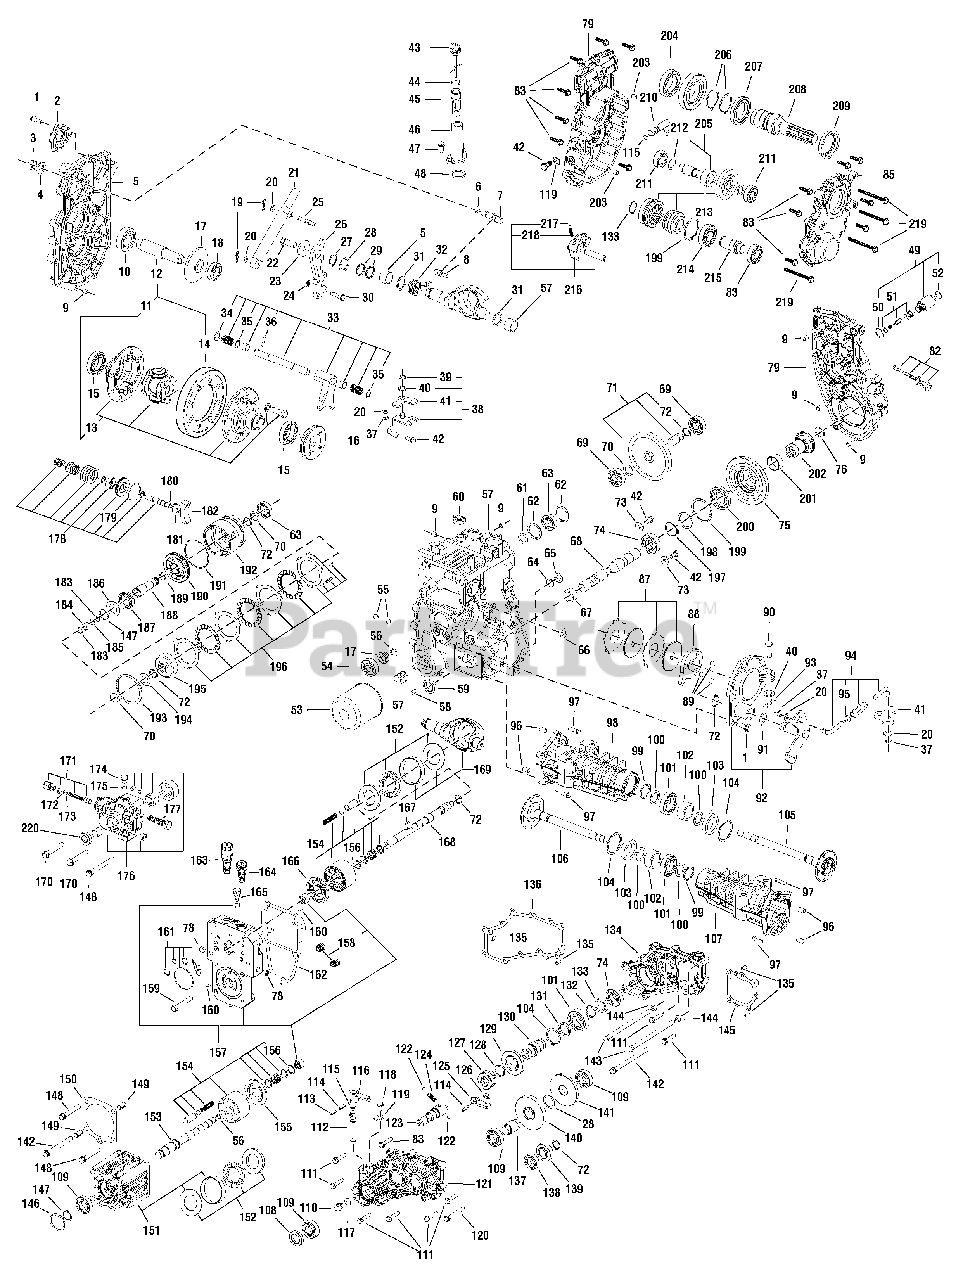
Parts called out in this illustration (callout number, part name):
2	COVER PTO BRAKE
5	COVER KIT MISSION
6	O-RING, 1A P10A
8	SPRING CENTERING
9	COLLAR 8*10*11.5
10	BEARING TMB305
11	FINAL GEAR KIT
12	SHAFT FINAL PINION
13	DIFF GEAR KIT
15	BEARING 6007
16	SLIDER DIFF LOCK
17	GEAR KIT INPUT
18	BEARING 6005SH2
21	ABSORBER SHOCK
23	WASHER 44*14*4.5
24	PUSH NUT 7.8
26	ARM CONTROL
28	WASHER 29*35*1
29	PACKING P26
30	PIN ARM CONTROL
31	WASHER 38*38*2
33	FORK KIT DIFF LOCK
34	SPACER 16.5*24*1
36	PIN 4.0A*25
38	FULCRUM KIT DIFF
44	PACKING P18
45	PIPE OIL PORT
47	TAPPING SCREW 8*20
48	PACKING P32
49	SOLENOID ASSY
50	GASKET SOLENOID
51	VALVE ASSY SOLENOID
52	PACKING P18
54	BEARING TMB303C
57	HOUSING KIT MISSION
59	SEAL TC253807
61	PACKING 19017
63	BEARING 6004
66	SEAL TC162606
67	NEEDLE 253216 NTN
68	SHAFT MID PTO
69	BEARING 6204
71	IDLE ASSY. PTO
73	WASHER 8.5*24*4
74	BEARING 6205
75	GEAR Z=62T MID PTO
79	CASE REAR PTO
82	PTO RELIEF VALVE KIT
85	REAR COVER PLATE
87	PLATE KIT BRAKE
91	PACKING P16
92	CAM BRAKE KIT
96	COLLAR 10*12*20
98	REAR AXLE HOUSING R
100	COLLAR 30*42*2
101	BEARING 6006
102	SLEEVE 30*39*16
103	SEAL TC395511
105	SHAFT REAR AXLE R
106	SHAFT REAR AXLE L
107	REAR AXLE HOUSING L
108	SEAL TC254208
109	BEARING 6005
110	BOLT M12*12
112	SHAFT SHIFT 4WD
113	PIN 3.5A*25
114	PIN 6.0A*25
115	PACKING P12.5
116	ARM SHIFT 4WD
117	GASKET 20*12*2
121	FRONT COVER
123	SHAFT FRONT DRIVE
124	SPRING 21.2
125	ARM SHIFT 4WD
126	BLOCK SHIFT FRONT
127	COLLAR FRONT SHIFT
129	GEAR 26T 4WD
131	COLLAR 30*38*4
133	COLLAR 30*38*9.2
134	CENTER PLATE
136	PK 4WD GEAR BOX
137	SHAFT REDUCTION 4WD
138	BEARING 6004
139	GEAR 13T MOTOR
140	GEAR 34T 4WD
141	GEAR 30T 4WD
142	BOLT 10*145
143	BOLT 10*180
145	PACKING FRONT COVER
148	BOLT 10*105
149	PIN KNOCK 12*22
150	PACKING MOTOR CASE
151	MOTOR CASE CMP.
152	BEARING SET THRUST
153	SHAFT MOTOR
154	BLOCK ASSY. CYL. P
155	PLATE VALVE M
157	CENTERCASE ASSY.
158	BODY ASSY. SUCTION
161	PACKING KIT
162	CENTERCASE PACKING
163	RELIEF ASSY. TOW 32
164	VALVE ASSY. CHECK R
165	RELEASE ASSY IMPLE
166	PLATE VAVLE P
171	VALVE ASSY.
174	PLUG 1/2OUNF
175	PACKING AS 905
176	BODY ASSY. PUMP
177	VALVE ASSY. REDUCING
178	BRAKE KIT PTO
179	PACKING 2045
180	PACKING P10
181	COLLAR BRAKE PIN
182	SHOE PTO BRAKE
184	NEEDLE 121718
185	WASHER 13*17*1
186	WASHER 25*42*2
187	SPRING PTO RETURN
188	SHAFT CLUTCH
189	RING SEAL 17203
191	PACKING G75
192	GEAR CLUTCH Z=39
194	WASHER 20*34*1
195	COLLAR SPLINE
196	DISC KIT FRICTION
198	SPACER CLUTCH SHAFT
200	BEARING 16007
201	NEEDLE 354017
202	COLLAR SPLINE
203	COLLAR 8*10*11.5
204	BEARING 6009
205	GEAR KIT 14-35
207	BEARING 16010
208	REAR PTO SHAFT
209	SEAL TCFY557214
210	SHAFT MBR CHANGE
211	BEARING 6204RSH2
212	SHAFT REAR PTO IDLE
213	GEAR KIT 20-29
214	BEARING 6206
215	SHAFT REAR PTO
216	FORK KIT MBR
220	SEAL, Charge Pump
